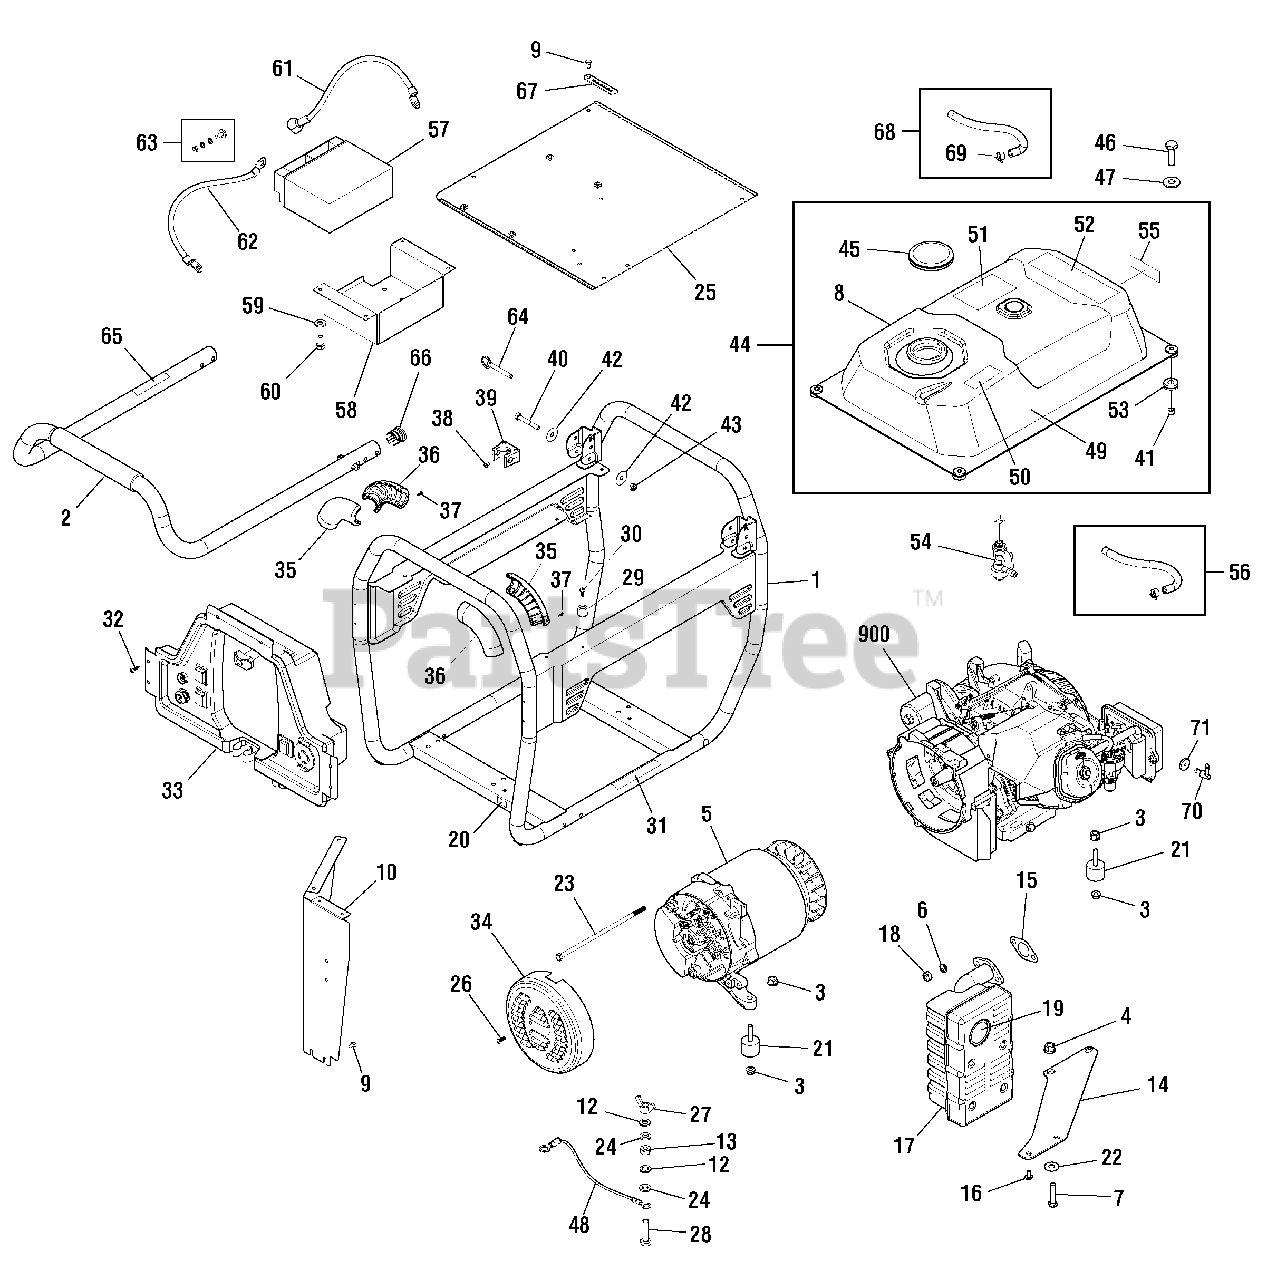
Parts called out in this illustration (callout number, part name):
5	ALTERNATOR
6	* WASHER, Lock, 3/8
7	* CAPSCREW, Hex Head, M10-1.5 x 45
9	* CAPSCREW, Hex Head, M6-1.0 x 10
12	* WASHER, Lock, 1/4
13	* NUT, M6-1.0
15	GASKET-EXHAUST
16	* CAPSCREW, Hex HEad, M6-1.0 x 12
18	* NUT, M8 - 1.25
21	MOUNT-VIBRATION
22	WASHER
24	* WASHER, M6
28	* CAPSCREW, Hex Head, M6-1.0 x 25
33	PANEL-CONTROL
34	COVER-REAR BEARING
44	TANK-FUEL
47	* WASHER, Flat, 1/4
56	KIT-FUEL HOSE (Cut to fit)
63	KIT-BATTERY HARDWARE
68	HOSE-VAPOR (Cut to fit)
900	** ENGINE
